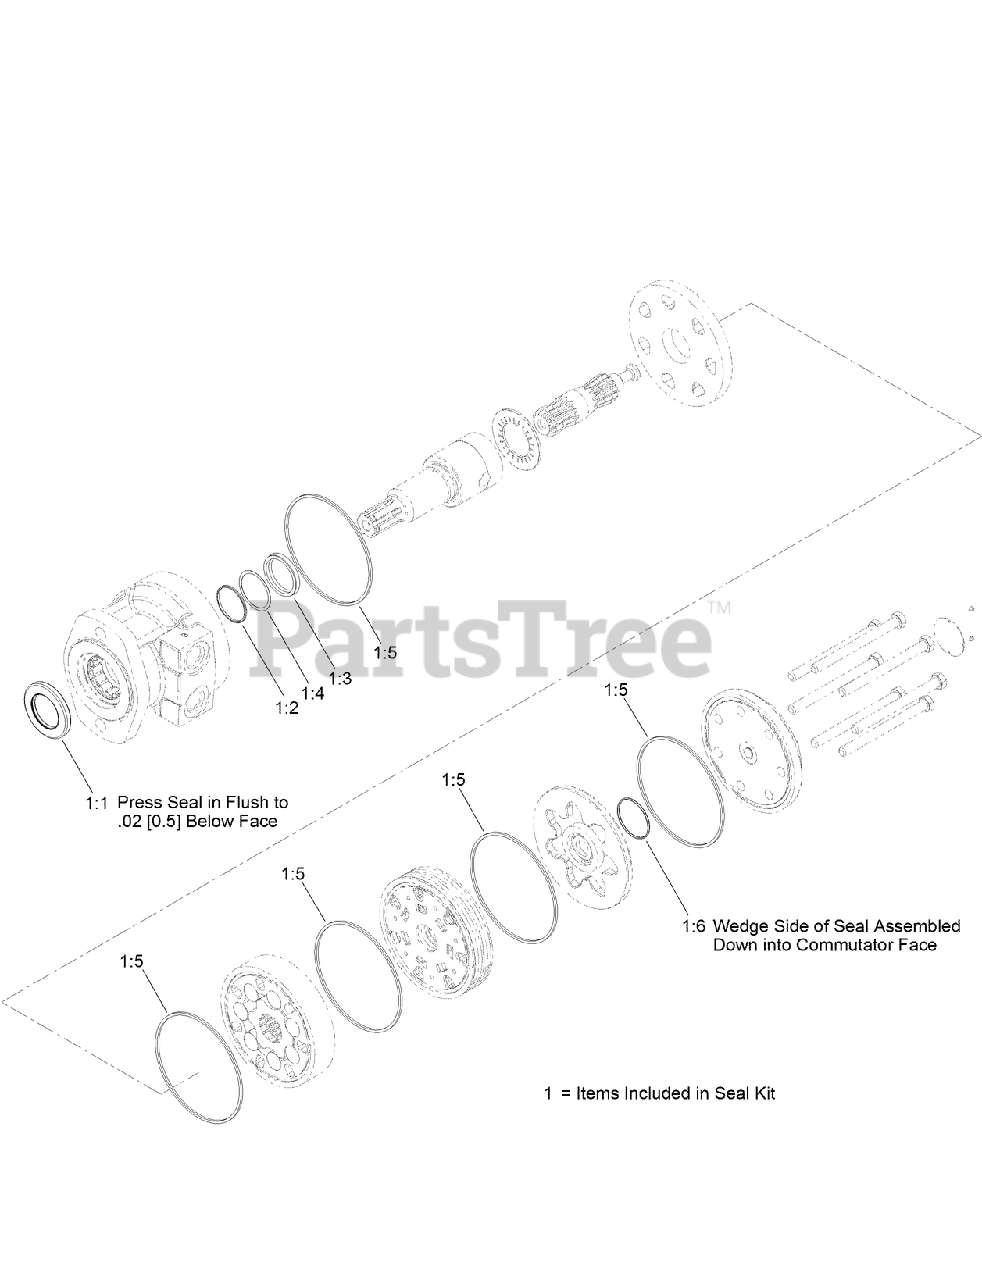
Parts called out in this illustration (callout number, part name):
1	SEAL KIT
1:1	Seal-Dirt and Water
1:2	BACKUP-RING
1:3	SEAL-Shaft
1:4	Washer-Back Up
1:5	SEAL-SQUARE, RING (INNER)
1:6	Seal-Commutator
